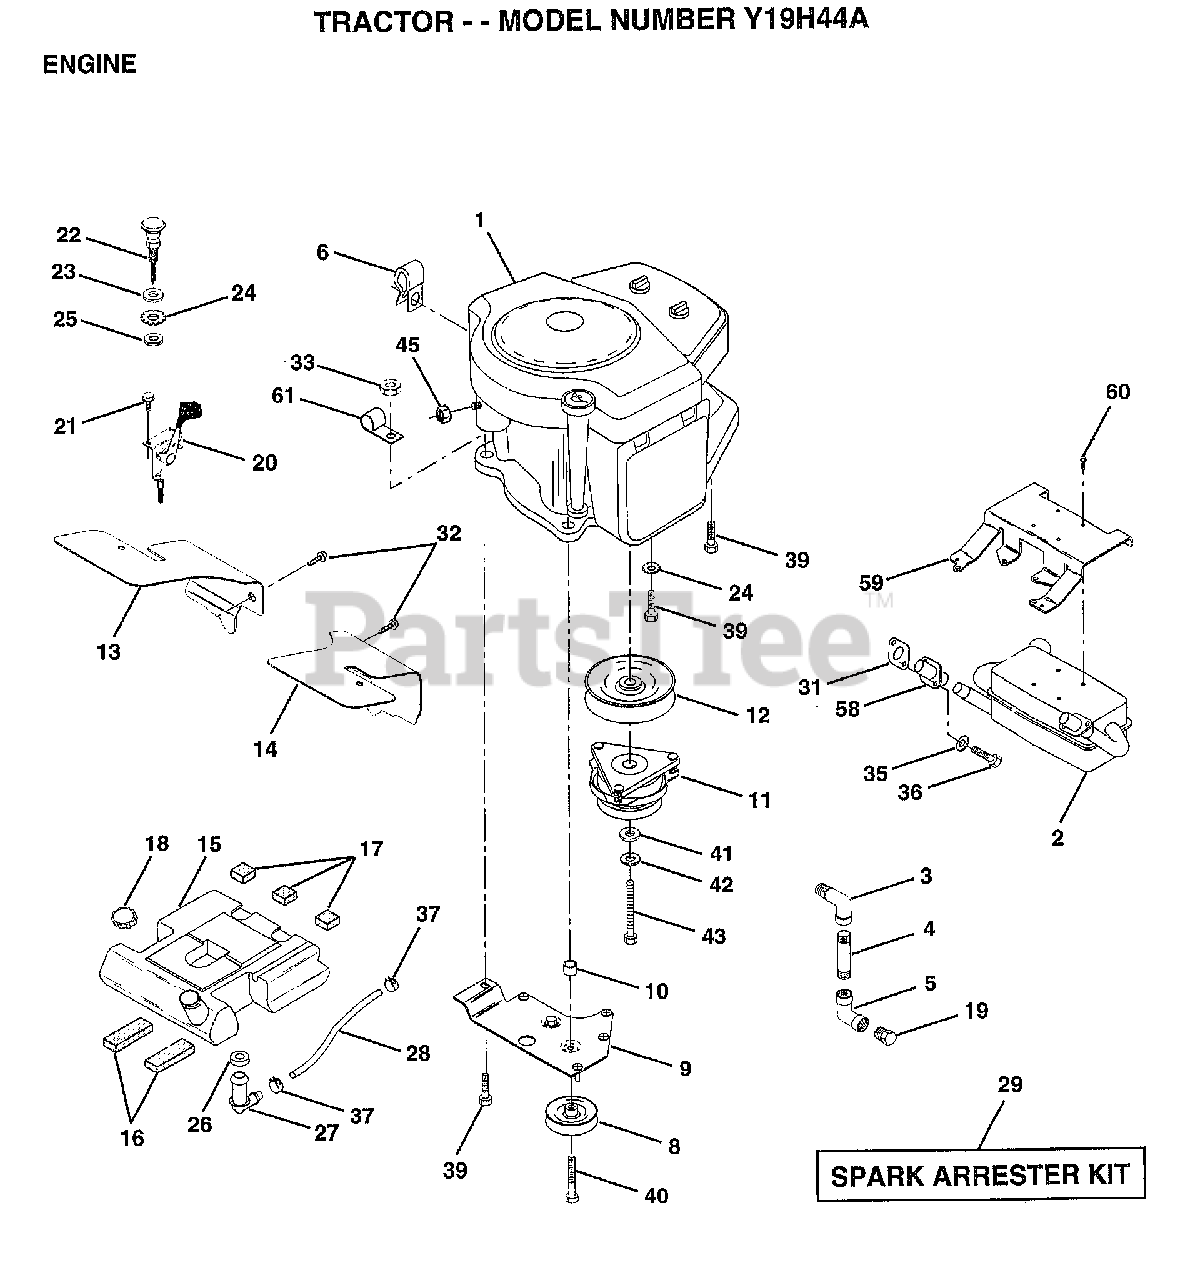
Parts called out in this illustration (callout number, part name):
2	MUFFLER.KOH.VCT.
3	STREET ELBOW LT
4	PIPE NIPPLE
5	ELBOW
6	CLAMP.TUBE.DBL.EN
10	BUSHING.
12	PULLEY.ENGINE.VGT
13	BAFFLE.AIR.LH.K
16	PAD IDLER TI
17	PAD-SPACER LT
18	CAP ASM FUEL
19	PLUG T
20	CONTROL THTL 37
21	SCREW LT
22	"CONTROL.CHOKE.51"""
23	WASHER
24	LOCKWASHER
26	BUSHING OUTLET T
27	STEM.TANK.FUEL
29	SPARK ARREST KIT
32	SCREW LT
35	LOCKWASHER
36	SCREW
37	HOSE CLAMP
39	SCREW LT
40	SCREW.3/8-16X3.25
41	WASHER
42	LOCKWASHER
45	NUT
58	LINER.PORT.EXHAUS
59	BRACKET.MUFFLER
60	SCREW ST
61	CLIP T
